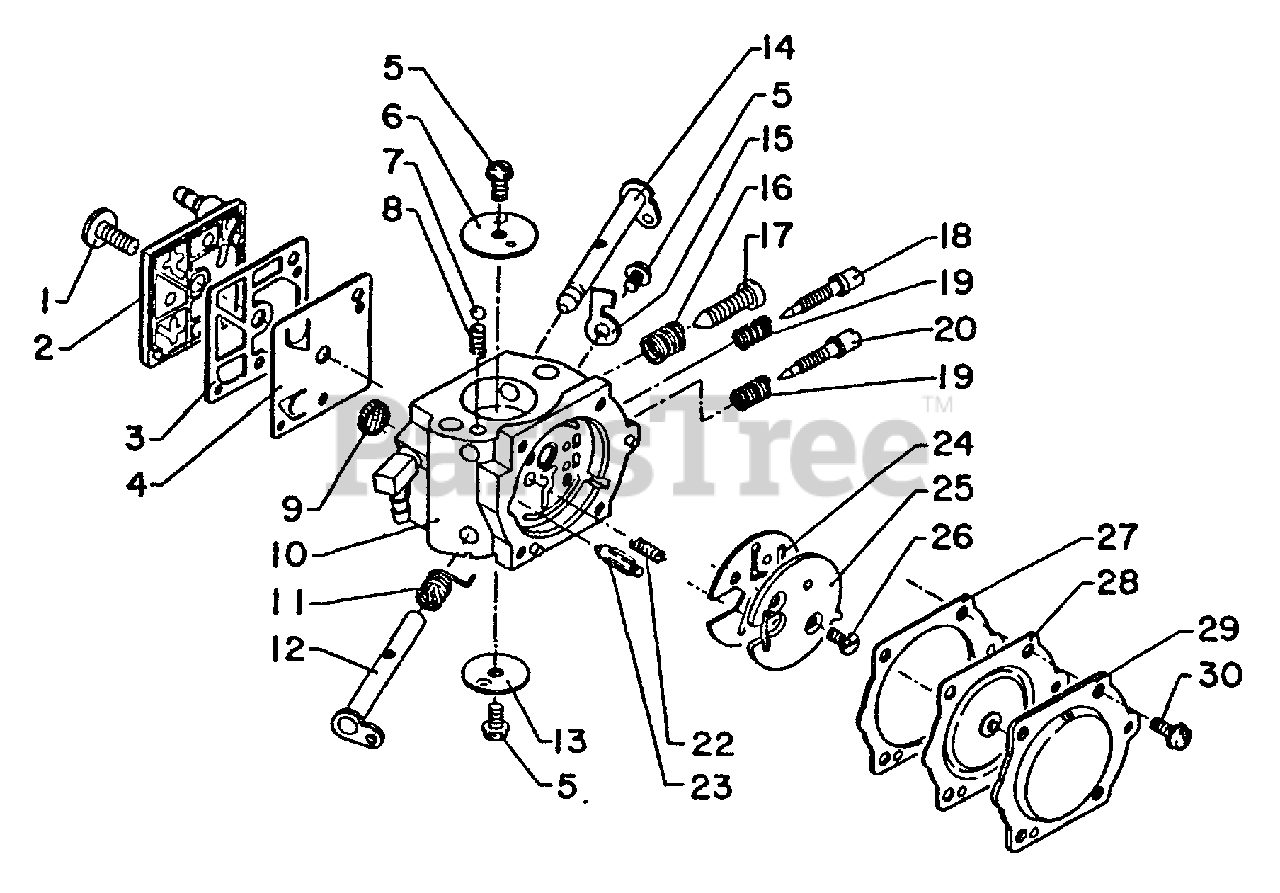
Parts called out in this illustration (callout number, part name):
1	SCREW, PUMP COVER
2	COVER, PUMP
3	GASKET, PUMP
4	DIAPHRAGM, PUMP
6	VALVE, CHOKE
7	BALL, CHOKE
9	STRAINER
10	BODY, CARBURETOR
11	SPRING, THROTTLE RETURN
12	SHAFT, THROTTLE
13	VALVE, THROTTLE
14	SHAFT, CHOKE
15	STOP, THROTTLE
16	SPRING, IDLE ADJUST
17	SCREW, IDLE ADJUST
18	NEEDLE - LOW SPEED
19	SPRING, IDLE ADJUST
20	NEEDLE - HIGH SPEED
22	SPRING, METERING LEVER
23	VALVE, INLET NEEDLE
24	GASKET, CIRCUIT PLATE
25	PLATE, CIRCUIT
26	SCREW, CIRCUIT PLATE
27	GASKET, METERING
28	DIAPHRAGM, METERING
29	COVER, DIAPHRAGM
